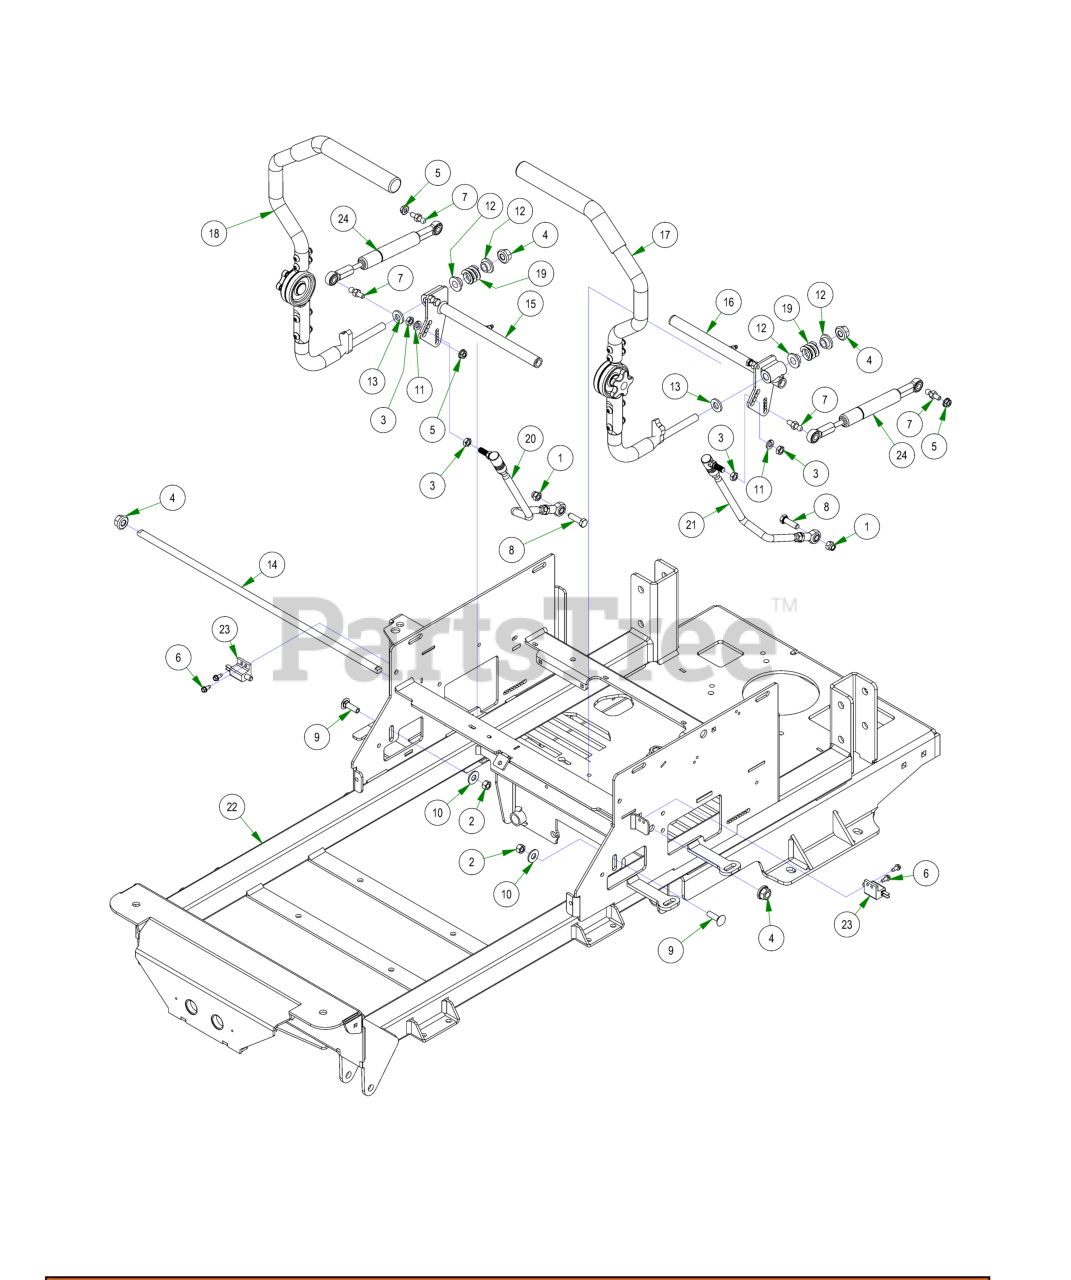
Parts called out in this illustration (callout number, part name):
1	3/8-16 NYLON INSERT LOCKNUT ZINC
2	3/8-16 HEX NUT ZINC
3	3/8-24 HEX NUT ZINC YELLOW
4	1/2-13 NYLON INSERT FLANGE LOCKNUT ZINC
5	5/16-18 HEX SERRATED FLANGE NUT HARD/ZINC
6	12-24 X 1/2 HEX WASHER UNLSOT F TCS ZINC
7	10mm Damper Ball Stud-Steering
8	3/8-16 X 1-1/4 HEX CAP SCREW (GR.5) ZINC
9	3/8-16 X 1-1/4 CARRIAGE BOLT ZINC
10	3/8 FLAT WASHER USS (1" OD) ZINC
11	3/8 SPLIT LOCKWASHER ZINC
12	.525 ID SHOULDER WASHER NYLON
13	.505 ID X 1.000 OD X .125 THICK FLAT WASHER NYLON
14	2021 Maverick Steering Actuator Rod
15	2021 Maverick Drive Arm Actuator RH Assembly
16	2021 Maverick Drive Arm Actuator LH Assembly
17	2018 Adjustable Steering Arm - Left
18	2018 Adjustable Steering Arm - Right
19	Drive Lever Spring
20	Push Rod-Right
21	Push Rod-Left
22	2023 Maverick Frame - Painted
23	Safety Switch
24	Steering Damper
